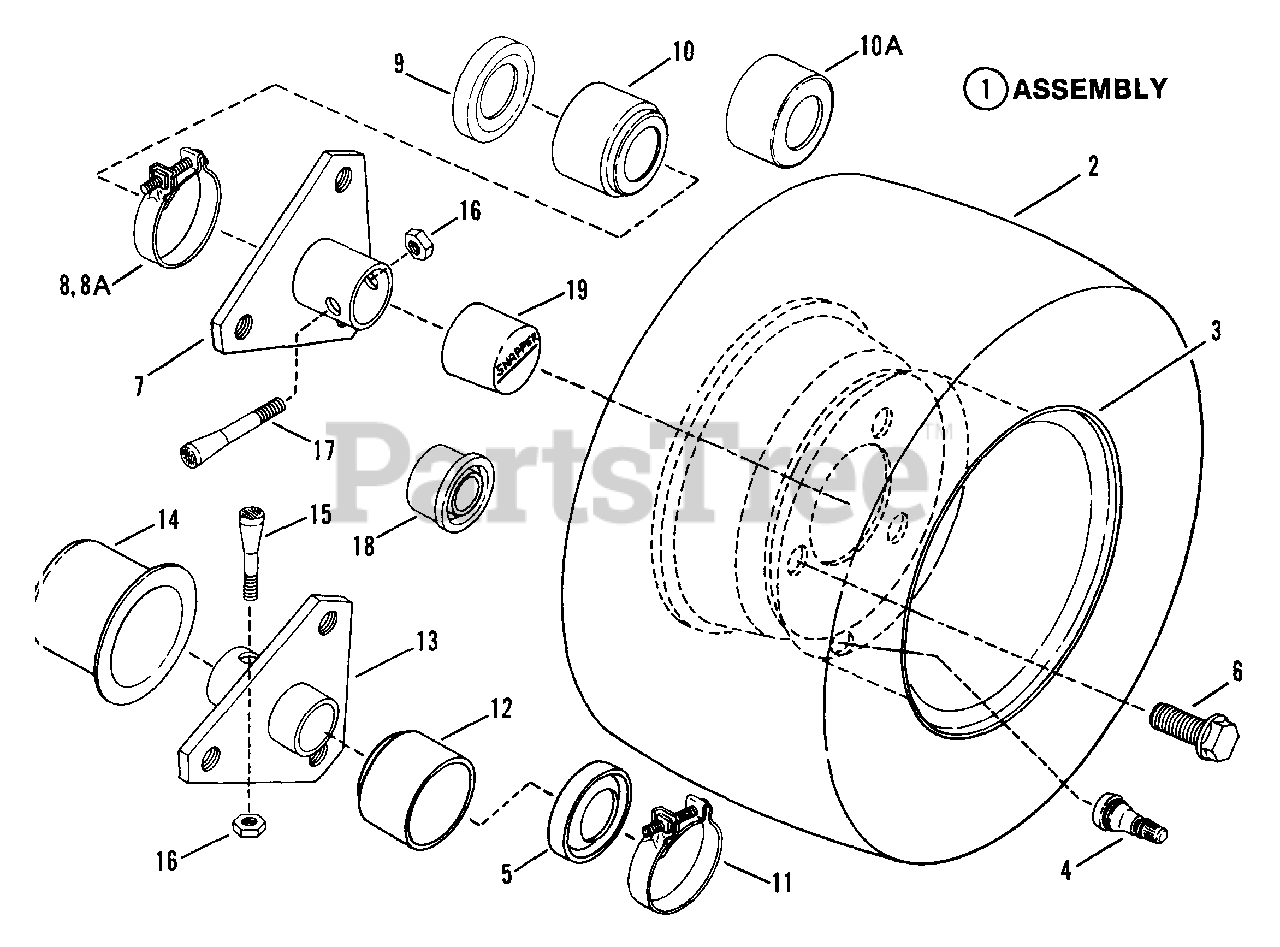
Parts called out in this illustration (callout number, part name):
1	ASSEMBLY, Rear Tire & Rim
2	TIRE, Wide, 16/6.50 x 8
2	TIRE, Std., 16/4.80 x 8
3	RIM, Wide, (For 16/6.50 x 8 Tire)
3	RIM, Std., (For 16/4.80 x 8 Tire)
4	VALVE, Air (Snap-In)
5	SEAL, OIL .750" ID x 1.832" OD (Left Hand)
6	BOLT, 1/2 - 20 x 3/4" Lug
7	HUB, Wheel RH, 3 Hole 1" ID
8	CLAMP, Right Hand 2.69"
8A	CLAMP, Right Hand 1.875"
9	SEAL 1.22" ID x 1.875" OD
10	BOOT, Right Hand (2.625" OD, 1" Hole)
10A	BOOT, Right Hand (1.687" OD, 1" Hole)
11	CLAMP, 2" (Left Hand)
12	BOOT, LH Ball Bearing Models 3/4"
13	HUB, Wheel LH, 3 Hole 3/4" ID
14	HUB-CAP, Left Hand
15	BOLT, 5/16 - 24 x 1-5/8" Tapered, Left Hand
16	NUT, 5/16 - 24 Lock
17	BOLT, 5/16
18	CAP, Seal L.H. Ball Bearing Models, 3/4"
19	HUB-CAP, Right Hand
